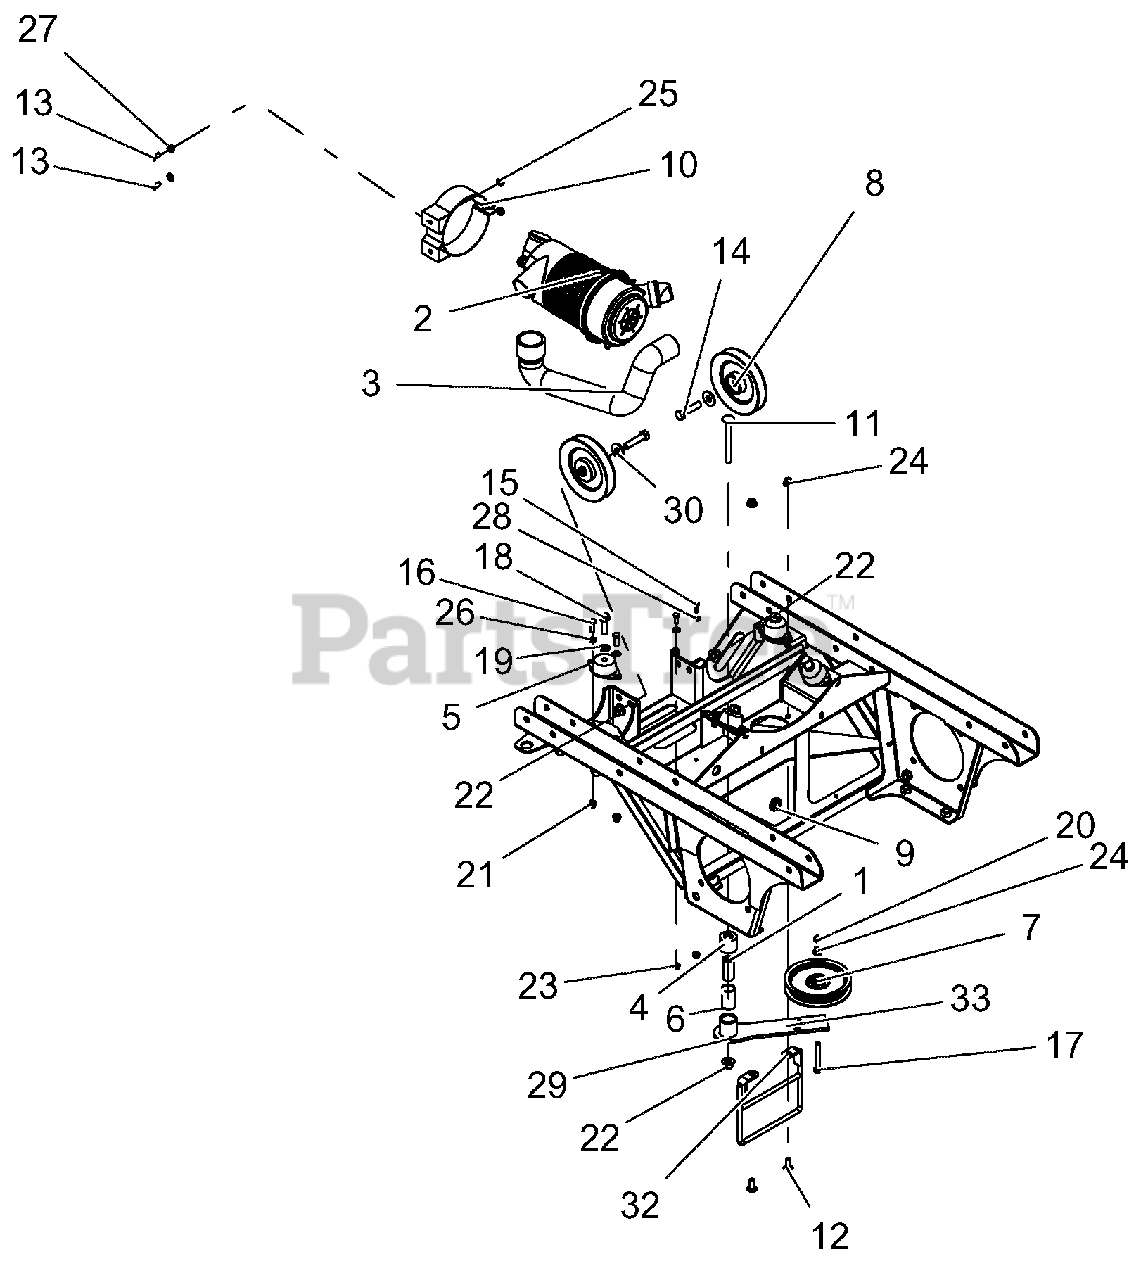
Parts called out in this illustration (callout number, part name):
1	BSHG, SPCR .502X.997X2.03
2	AIR, CLEANER
3	HOSE, FORMED AIR CLEANER OUTLET
4	SPCR, PT400 DIESEL IDLER ARM
5	MOUNT, ENGINE. VIBRATION ISO
6	BSHG, 1.00X1.125X1.937
7	IDLER, FLAT 5.00 X 3.8
8	PULLEY, V-IDLER 6.0X.500 ID DBL BRG
9	GROMMET, RUBBER
10	BRKT, AIR CLEANER MOUNT
11	@BLT-RDHDSQNK .50-13X4.50 G5 YWZC
12	@BLT-RDHDSHSQNK.38-16X1.0 G5YZ
13	BLT-HEX .31-18X.75 GR5 YWZC
14	BLT-HEX .50-13X2.25 GR5 YWZC
15	BLT-HEX .25-20X.75 GR5 YWZC
16	BLT-HEX .31-18X1.00 GR5 YWZC
17	BLT-HEX .38-16X2.75 GR5 YWZC
18	BLT-HEX .50-20X1.50 GR5 YWZC
19	@WSHR-LK .50X.125 REG YWZC
20	@NUT-LK-CTR .38-16 YWZC
21	NUT-LK-NYL-FLG .31-18 YWZC
22	NUT-LK-NYL-FLG .50-13 YWZC
23	NUT-LK-NYL-FLG .25-20 YWZC
24	NUT-LK-NYL-FLG .38-16 YWZC
25	@NUT-SPNLK-FLG .312-18 YWZC
26	@WSHR-FL-STL.344X.688X.065YWZC
27	@WSHR-FL-STL.406X.812X.065 YWZ
28	@WSHR-FL-STL.281X.62X.065 YWZC
29	@WSHR-FL-STL.531X1.06X.095YWZC
30	@WSHR-FL-STL.563X1.38X.109YWZC
32	WLDMT, DIESEL BELT FINGER
33	WMT, IDLER ARM GROUND
